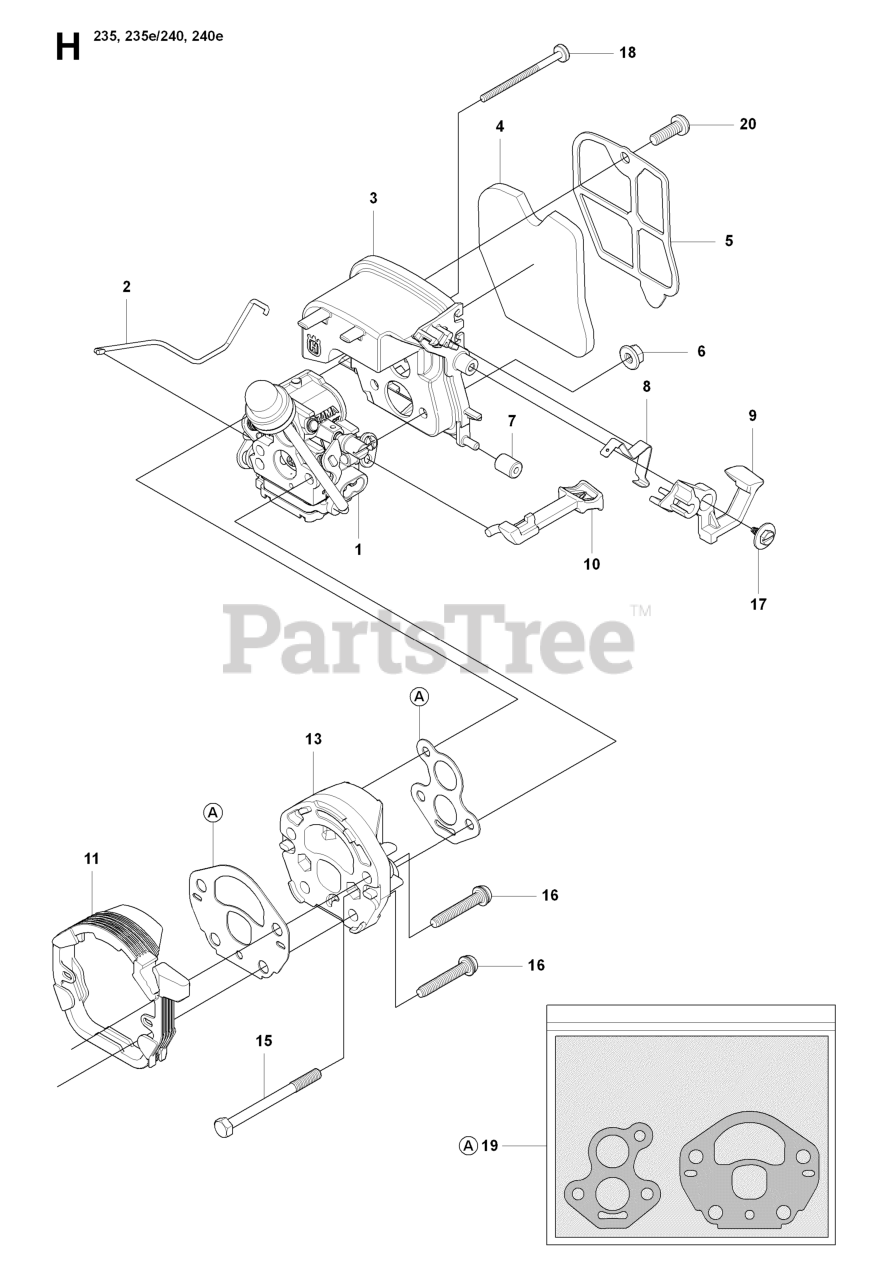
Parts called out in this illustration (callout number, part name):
1	%CARBURETOR
2	THROTTLE WIRE
3	FILTER HOUSING
4	AIR FILTER
7	ISOLATOR FILTER HOUSING
9	SWITCH LEVER
10	CHOKE KNOB
11	CARB ADAPTOR SEAL
13	CARB ADAPTOR
15	STUD CARBURETOR
18	TOP STUD - CARBURETOR
19	GASKET KIT
20	SCREW FILTER PLATE
